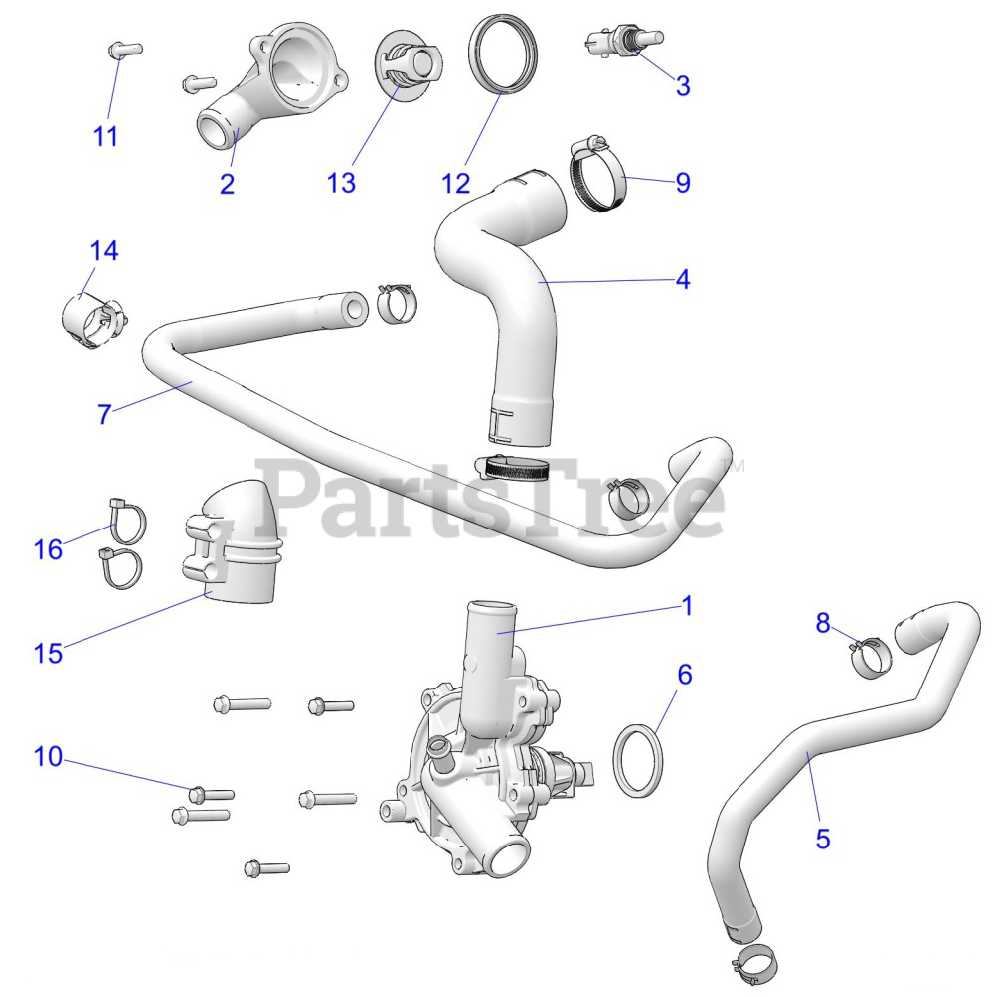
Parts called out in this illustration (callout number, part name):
1	ASM-WATER PUMP
2	COVER-THERMOSTAT
3	SENSOR-THERMISTER
4	HOSE-WATERPUMP-OUT
5	HOSE-OIL COOLER OUT
6	FILTER-WP
7	HOSE-BYPASS LINE
8	CLAMP- HOSE- SPRING
9	CLAMP-HOSE(WORM DR)25-40MM
10	SCR-HXFL-M6X1.0X35-W/PATCHLOK
11	SCR-M6X20-HXFLG-0600214
12	SEAL-THERMOSTAT
13	THERMOSTAT-44M FLANGE-180F
14	CLIP-HOSE
15	SUPPORT-STATOR WIRE
16	CABLE TIE (10)
